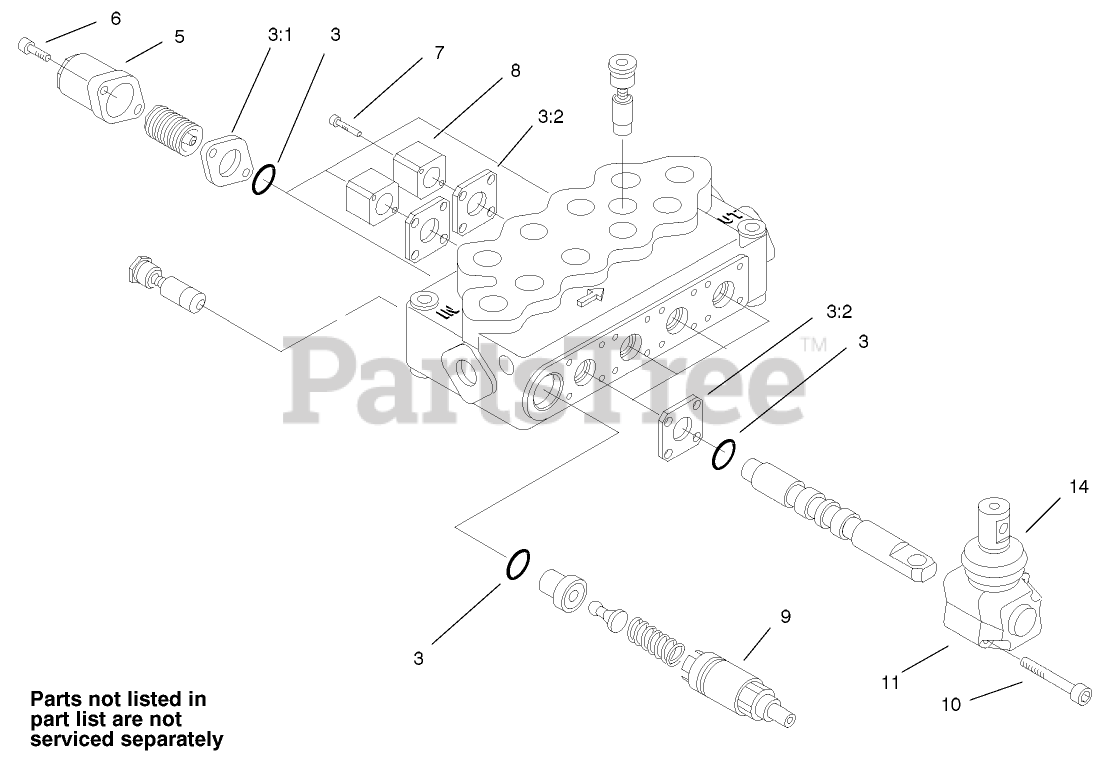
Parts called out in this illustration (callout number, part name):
3	SEAL KIT
3:1	GASKET
3:2	GASKET
5	HIGH FORCE SPRING KIT
6	SCREW-CAP, END
8	BLOCK-MOUNT, SWITCH
9	VALVE-RELIEF
11	OPERATOR ASM
